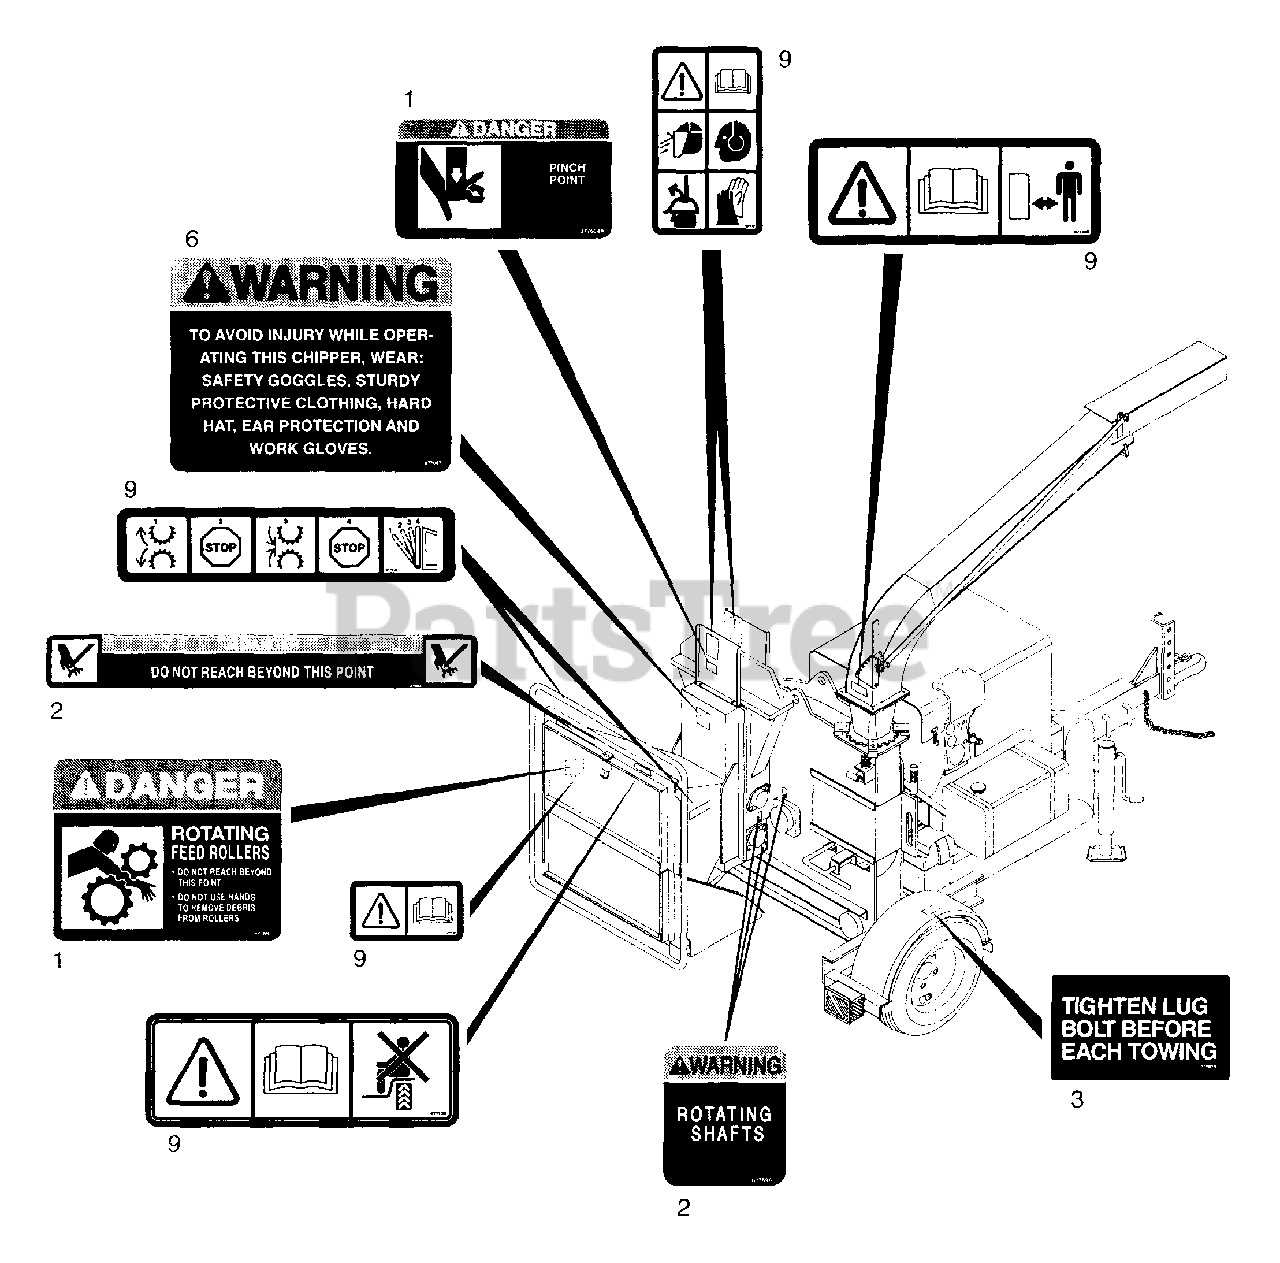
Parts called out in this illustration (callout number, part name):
1	Decal-Set
2	Decal-Set Large Chippers
3	Decal-Set Chipper Black/White
6	Decal-Warning-Protective
9	Decal-Set Chipper CE
